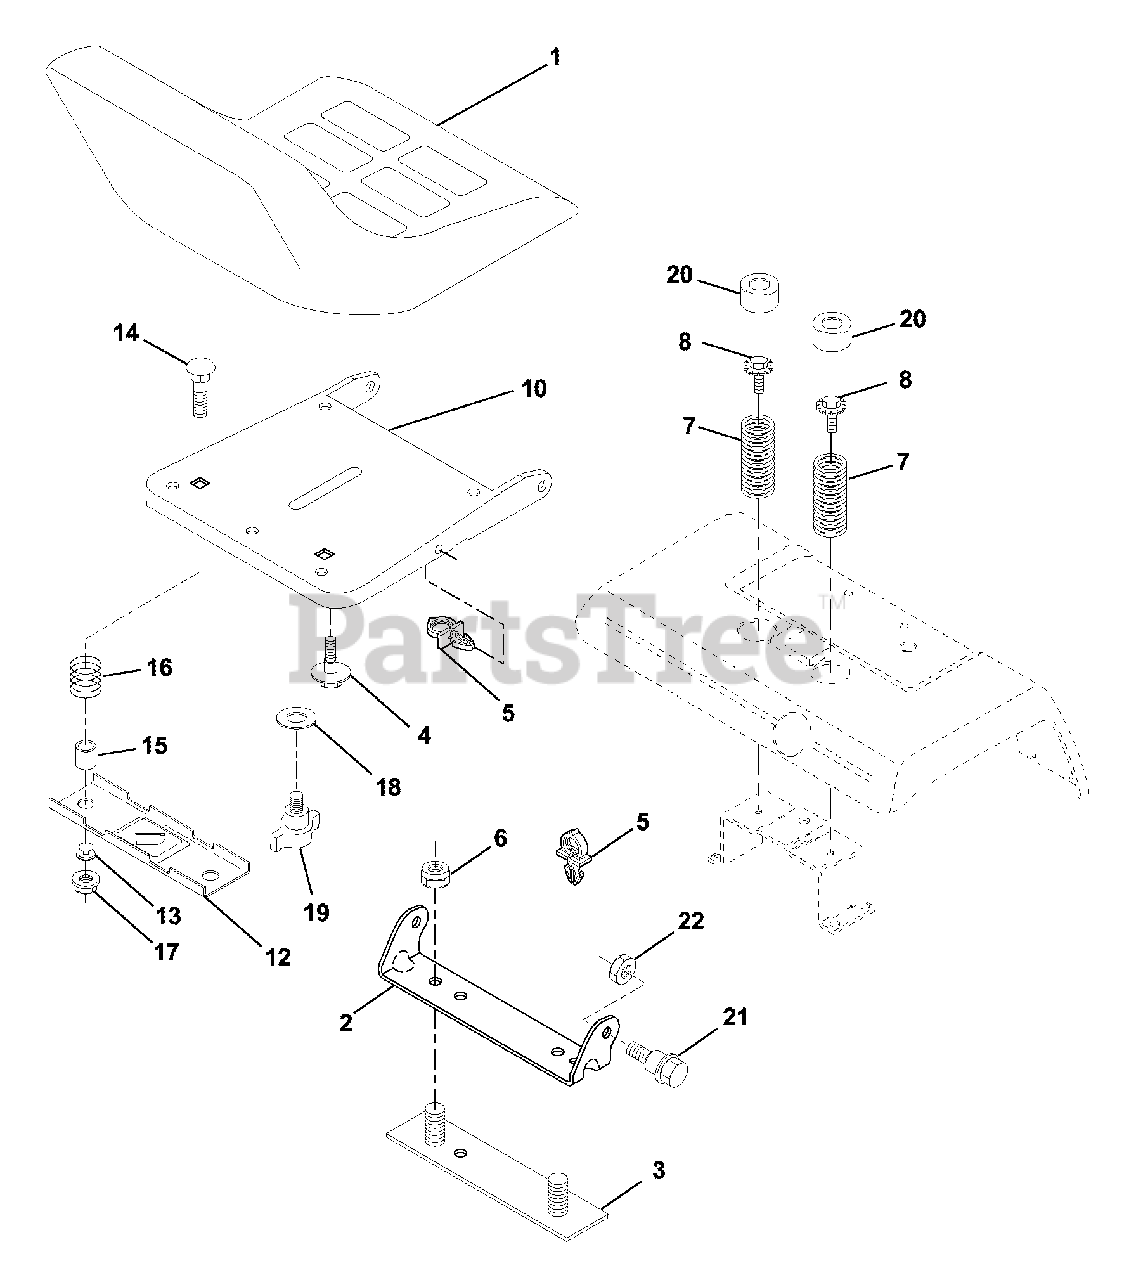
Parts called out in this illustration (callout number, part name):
1	Seat
2	Bracket, Pivot Seat
3	Strap, Fender
4	Bolt, Shoulder 5/16-18 X .62
5	Clip, Push In Hinged
6	Nut, Crownlock 3/8-16
7	Spring, Seat Cprsn
8	Bolt 5/16-18 UNC X 3/4
10	Pan, Seat
12	Bracket, Mounting Switch
13	Bushing, Snap
14	Bolt, Carriage 114-20 X 1-1 /2
15	Spacer, Split
16	Spring, Cprsn
17	Nut, Lock 1/4 Lge Fig Gr. 5
18	Washer 17/32 X 1-3/16 X 12 Ga.
19	Knob, Seat
20	Cap, Spring Seat
21	Bolt, Shoulder 5/16-18
22	Nut, Crownlock 5/16-18
